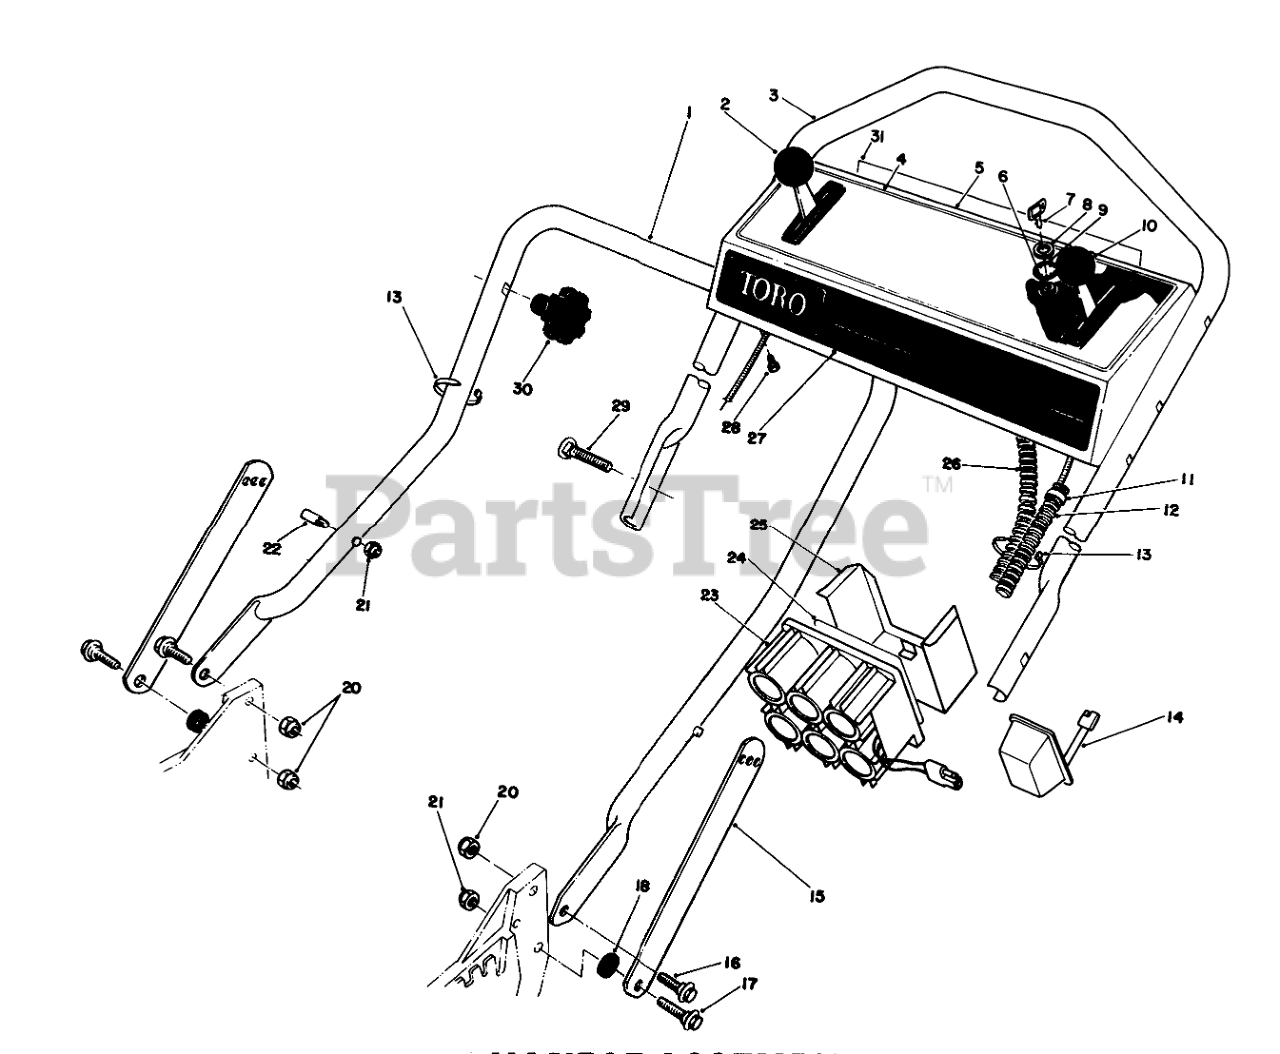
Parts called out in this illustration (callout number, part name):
1	LOWER HANDLE ASM
2	GROUND SPEED CONTROL
3	Handle-Upper
4	Decal-Instruction Panel
5	Panel-Control (Incl. Ref. #4 & 31)
6	Switch-Starter (Incl. Ref. #8-9)
7	KEY-IGNITION
9	WASHER-TOOTH, INTERNAL
10	THROTTLE CONT-SERVICE
11	FITTING-RING
12	CONTROL CABLE COVER
13	TIE-CABLE
14	Charger
15	Handle Latch
16	SCREW-SHOULDER
17	SCREW-SHOULDER
18	SPACER
20	NUT-LOCK, NI
21	NUT-LOCK, NI
22	HANDLE PIN
23	BATTERY ASSEMBLY
24	Decal
25	Retainer-Battery
26	WIRE HARNESS
27	DECAL - KEY LECTRIC
28	SCREW-HWHTF
29	5/16-18 X 2 HNDLE SCREW
31	DECAL - PANEL, REAR
